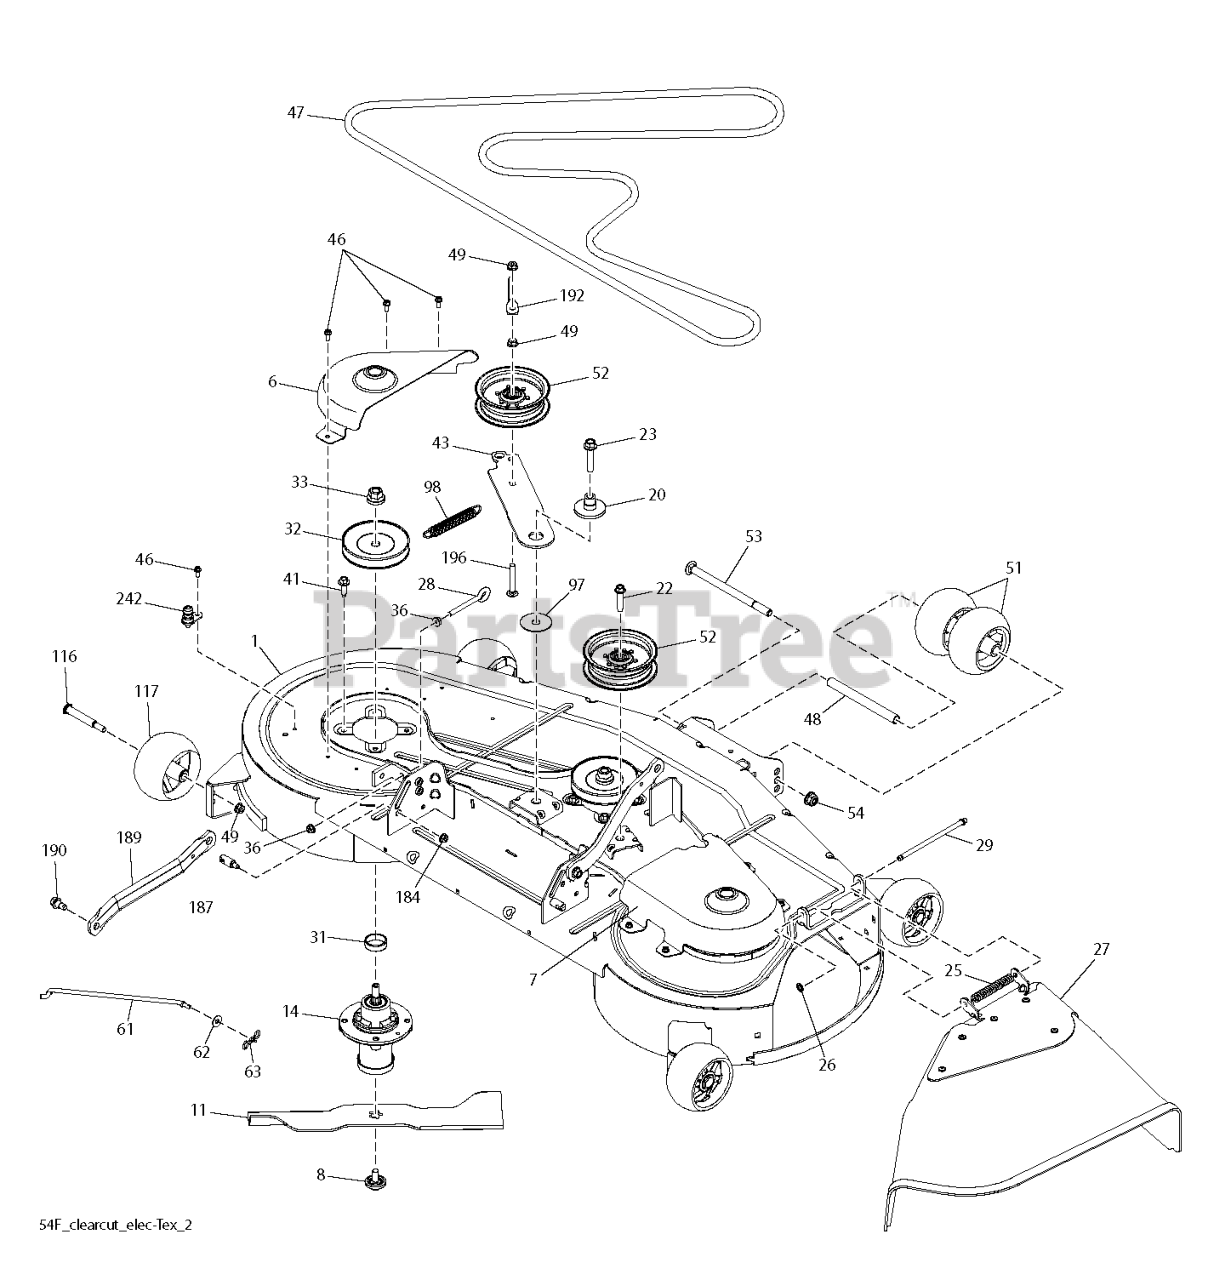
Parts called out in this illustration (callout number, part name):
1	KIT.SVC.WELDMENT.54CC.428
6	COVER 54 CLEARCUT, LH MANDREL,
7	COVER 54 CLEARCUT RH MANDREL B
8	BOLT.WASHER.ASM.7/16-2
11	BLADE CC54 PZ STYLE HI LIFT BL
14	MANDREL ASM, CAST IRON
20	SPACER.IDLER.PULLY.HUB
22	SCREW LT
23	SCREW.7/16-14 X 2.125.WASHER
25	SPRING.42.FCS.DEFLECTOR
26	NUT PUSH M
27	DEFLECTOR ASSY 54 CLEARCUT RES
28	EYE BOLT 5/16 X 3.50
29	FLAT IDLER PULLEY
31	WASHER.SPACER.MANDREL
32	PULLEY MANDREL
33	NUT.FLANGE.LOCK.TOP
36	NUT 5/16C WHIZ
41	BOLT.HEX.WASHR.HED.313-18X1.19
43	ARM IDLER ARM, CLEARCUT 54 BLA
46	SCREW.1/4-20X5/8
47	BELT CLEARCUT 54, TRACTOR DECK
48	TUBE, ROLLER AXLE LONG
49	NUT LOCK FLG 3/8-16 UNC
51	ROLLER, GAUGE .635 BORN
52	PULLEY.IDLER.2006
54	NUT, 1/2-13 HEX FLG NYLOC ZD
61	ROD.ANTI.SWAY.48/54"TE
62	WASHER
63	PIN.COTTER.5/16.BOW TI
98	SPRING.EXTN.42.FCS.TR.DECK.DRV
116	BOLT.SHOULDER.3/8-16X3-5/8.
117	WHEEL. GUAGE RALLY
184	NUT LOCK HEX FLANGE 5/16-18
187	STUD.FASTNER.W/ANTI-ROTATE
189	ARM.SUSPENSION.MOWER
190	BOLT.SHOULDER
192	KEEPER.BELT.IDLER.54"T
196	BOLT
242	PORT.WASHOUT
